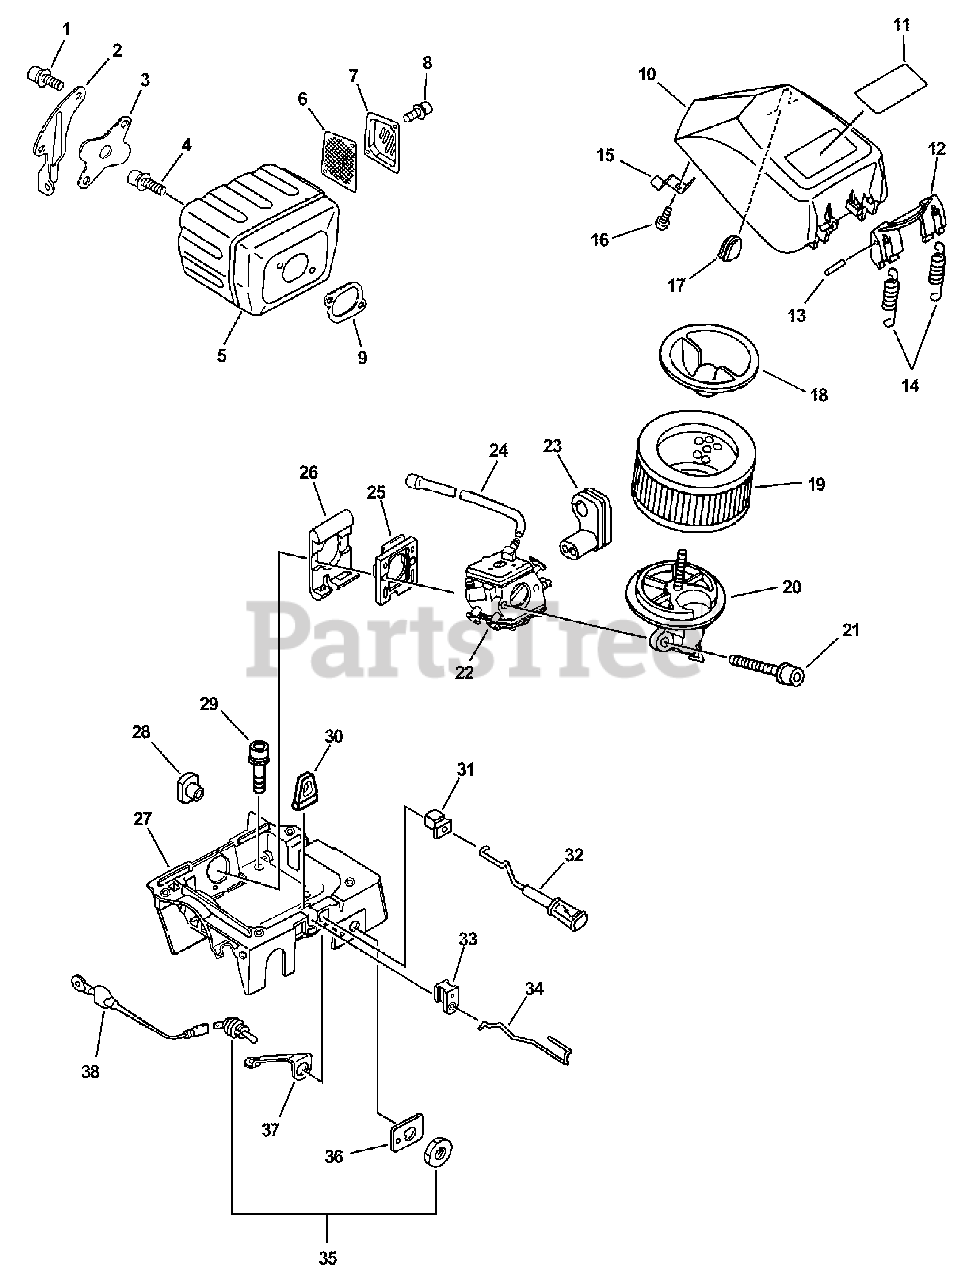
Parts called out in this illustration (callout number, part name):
1	SCREW - 5X14
2	BRACKET, MUFFLER
3	COVER, MUFFLER
4	SCREW - 5X20
5	MUFFLER
6	SCREEN, SPARK ARRESTOR
7	GUIDE, EXHAUST
8	SCREW - 4X10
9	GASKET, EXHAUST
11	LABEL - MODEL QV-670
12	COVER, AIR FILTER
13	PIN - 3X12
15	SPRING, FLAT
16	SCREW - 4X10
18	COVER, AIR FILTER
19	FILTER, AIR
20	MOUNT, AIR FILTER
21	SCREW - 5X50
22	CARBURETOR
23	GROMMET
24	PIPE - IMPULSE
25	INSULATOR, INTAKE
26	BRACKET
27	CASE, CARBURETOR
29	SCREW - 5X20
30	CUSHION
32	ROD, CHOKE
33	GUIDE, THROTTLE ROD
34	ROD, THROTTLE
35	IGNITION SWITCH ASSY
36	LABEL - STOP
37	TERMINAL - GROUND
38	LEAD - GROUND
